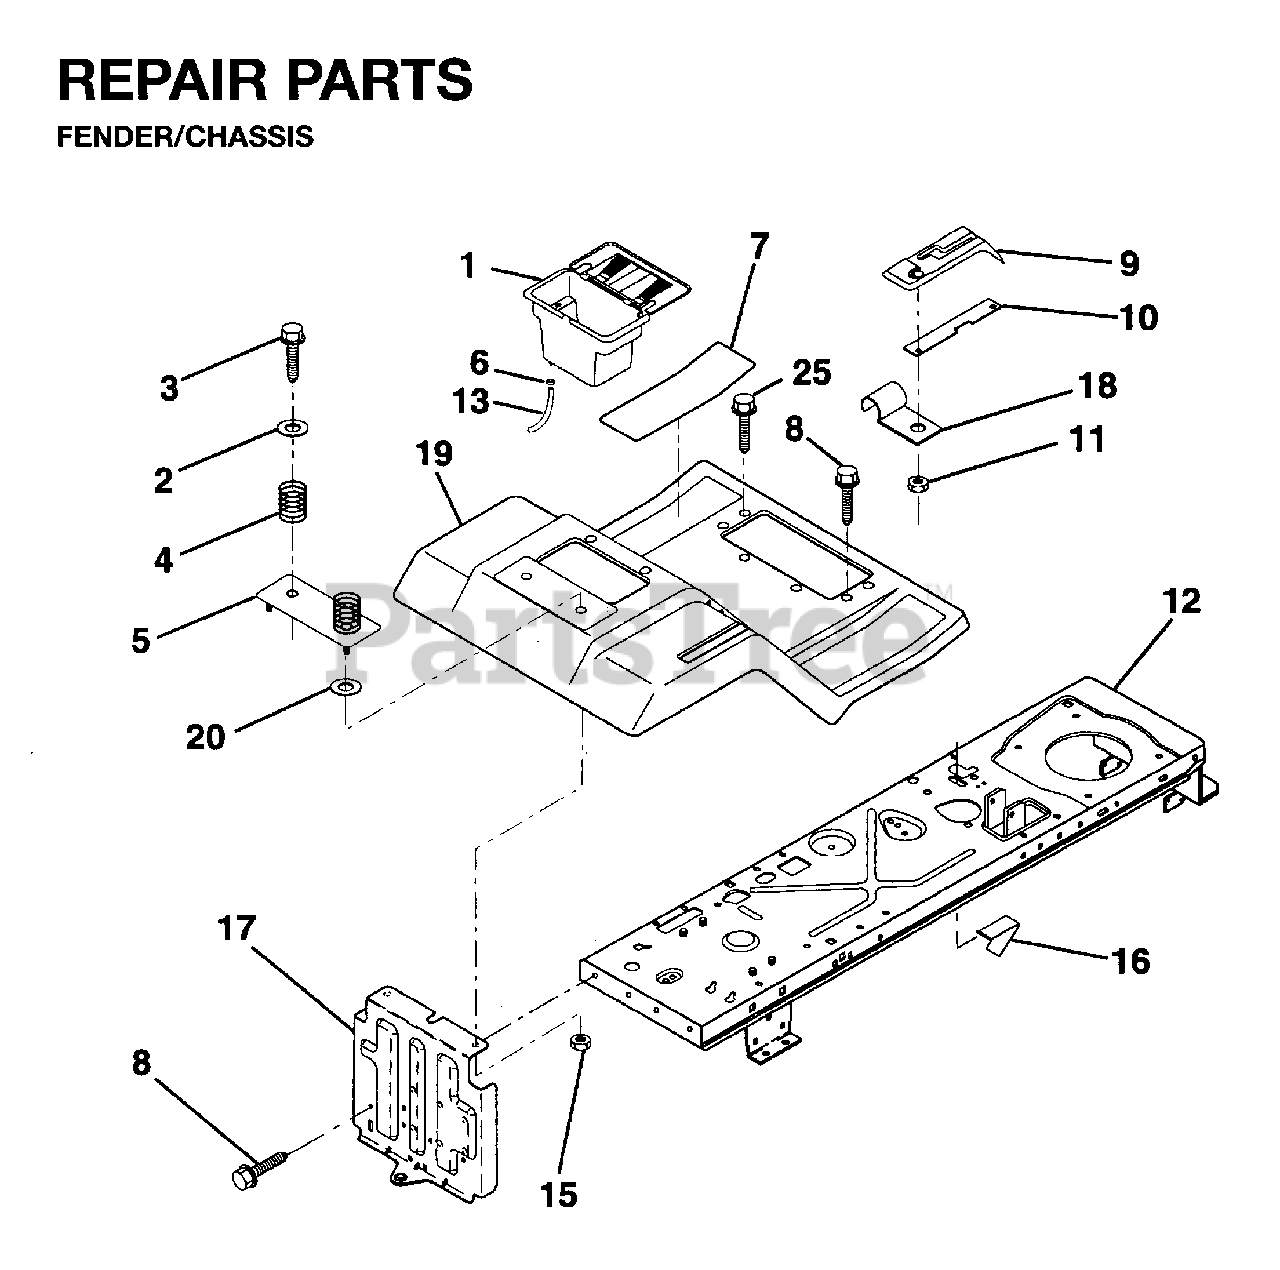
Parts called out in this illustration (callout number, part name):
1	CASE BATTERY
4	SPRING COMPRESSION
6	HOSE CLAMP T
7	PAD FOOTREST
8	BOLT
9	CONSOLE SHT CONTR
10	BAR, SHIFT LOCK
13	TUBE BATTERY DRAIN
15	NUT.CROWNLOCK.1/4
18	CLIP,INSULATOR
25	SCREW
